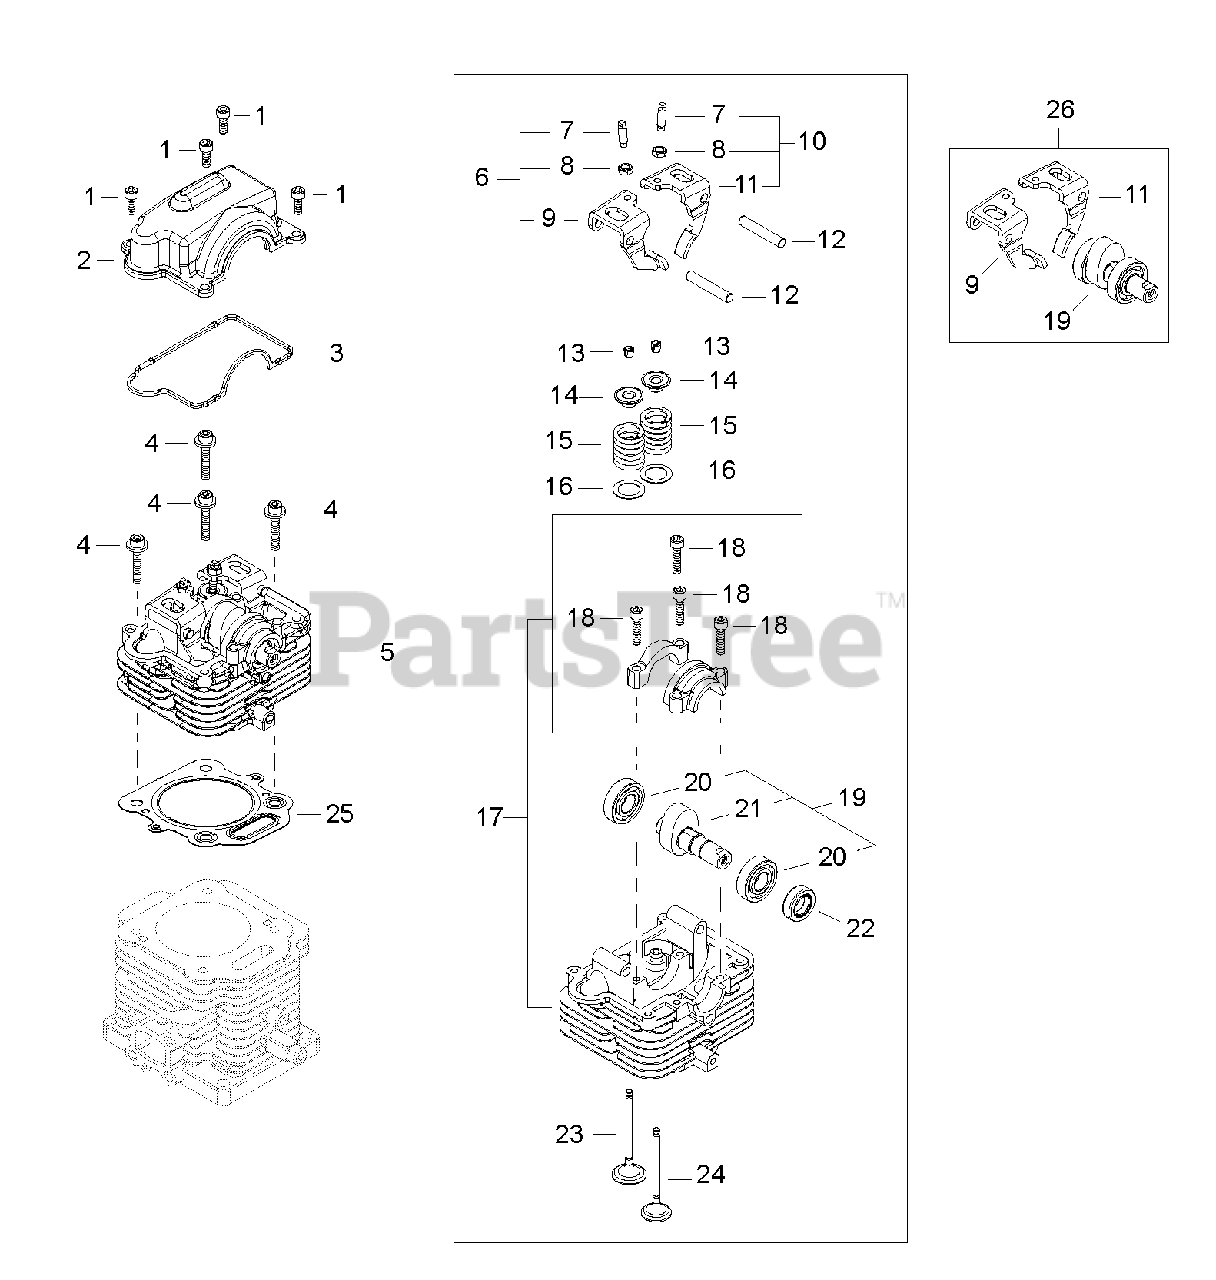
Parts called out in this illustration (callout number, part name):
1	BOLT 5×16
2	COVER, VALVE
3	GASKET, VALVE COVER
4	BOLT, FLANGE M6×35
5	HEAD ASSY, CYLINDER
6	CAM FOLLOWER ASSY, RIGHT
7	SCREW, ADJUSTER
8	NUT, ADJUSTER LOCK 5
9	FOLLOWER, CAM LEFT
10	CAM FOLLOWER ASSY, LEFT
11	FOLLOWER, CAM RIGHT
12	SHAFT, CAM FOLLOWER 6
13	KEEPER, VALVE
14	RETAINER, VALVE
15	SPRING, VALVE
16	WASHER, VALVE 13
17	HEAD, CYLINDER
18	BOLT M5×22
19	CAMSHAFT ASSY
20	BEARING, BALL 6001
21	CAMSHAFT
22	SEAL, OIL 12
23	VALVE, INTAKE
24	VALVE, EXHAUST
25	GASKET, CYLINDER HEAD
26	CAM KIT
